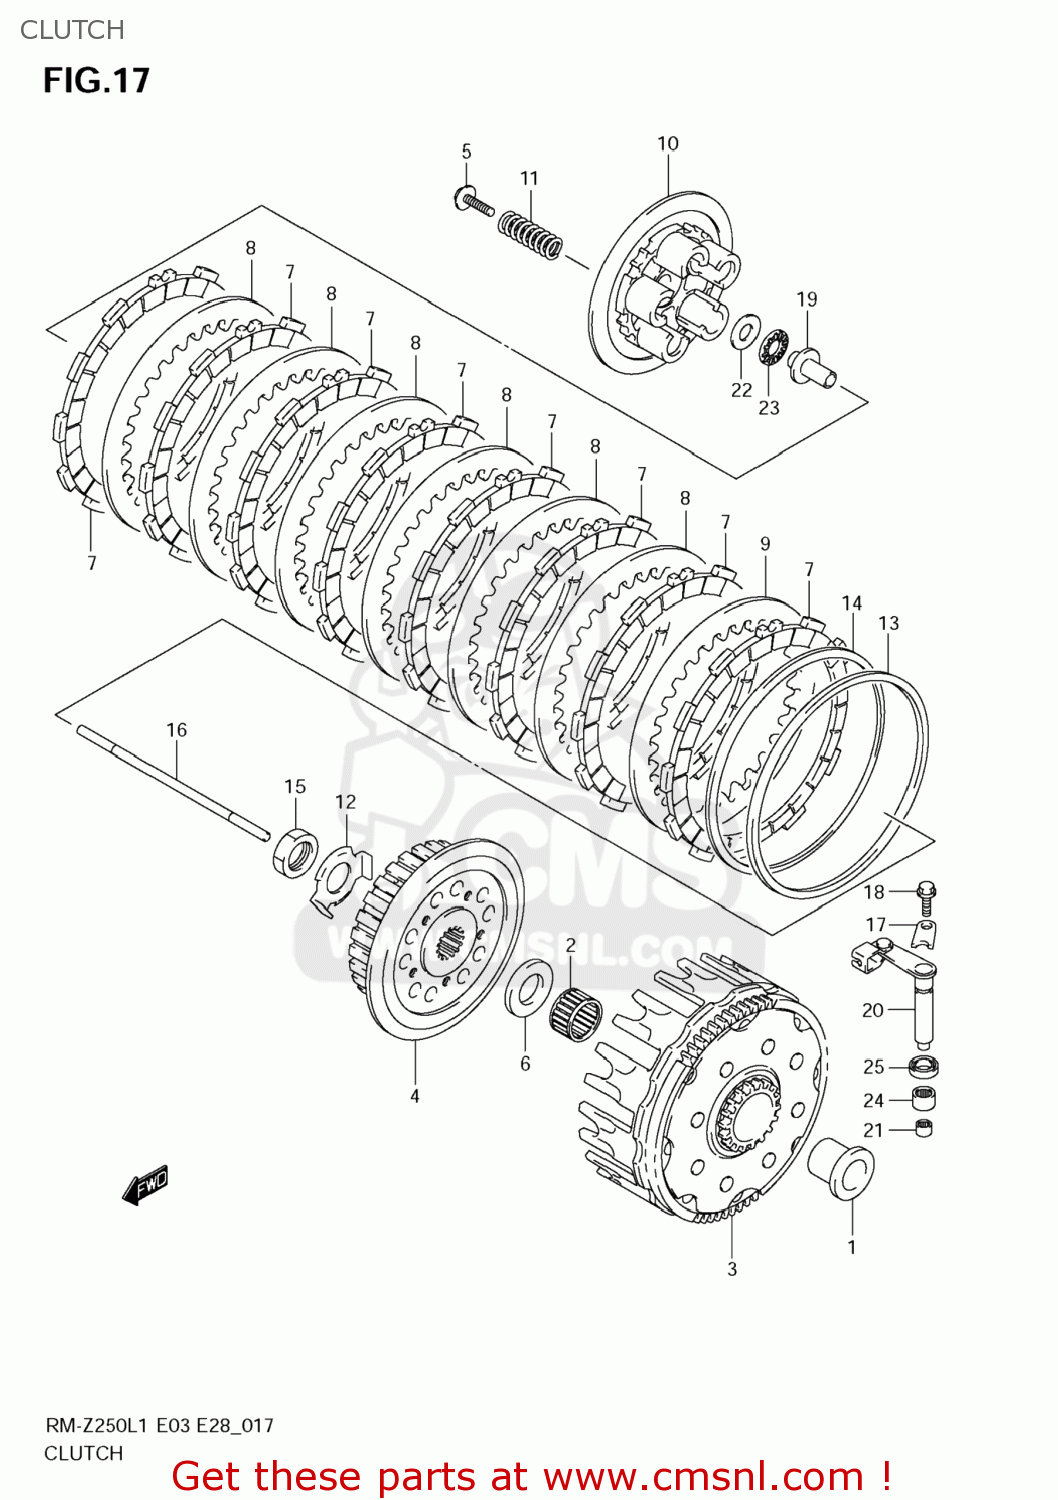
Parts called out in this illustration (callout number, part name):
1	SPACER,PRIMARY DRIVEN GEAR
2	BEARING(27X32X21.8)
3	GEAR ASSY,PRI DRIVEN
4	HUB,CLUTCH SLEEVE
5	BOLT,CLUTCH SPRING
6	WASHER(22X45X3)
7	PLATE,CLUTCH DRIVE NO.2 (NAS)
8	PLATE,CLUTCH DRIVEN (NAS)
9	PLATE,CLUTCH DRIVEN (NAS)
10	DISC,CLUTCH PRESSURE
11	SPRING,CLUTCH
12	WASHER,CLUTCH SLEEVE HUB LOCK
13	SEAT,CLUTCH PLATE WAVE WASHER
14	WASHER,CLUTCH PLATE
15	NUT
16	ROD,CLUTCH PUSH
17	RETAINER,CL RELEASE CAMSHAFT
18	BOLT(6X12)
19	PIECE,CLUTCH PUSH
20	CAMSHAFT,CLUTCH RELEASE
21	BEARING,CLUTCH RELEASE(7X11X9)
22	SHIM(12X26X0.8)
23	BEARING(12X26X2)
24	BEARING(10X14X10)
25	SEAL,OIL(10X17X5)
